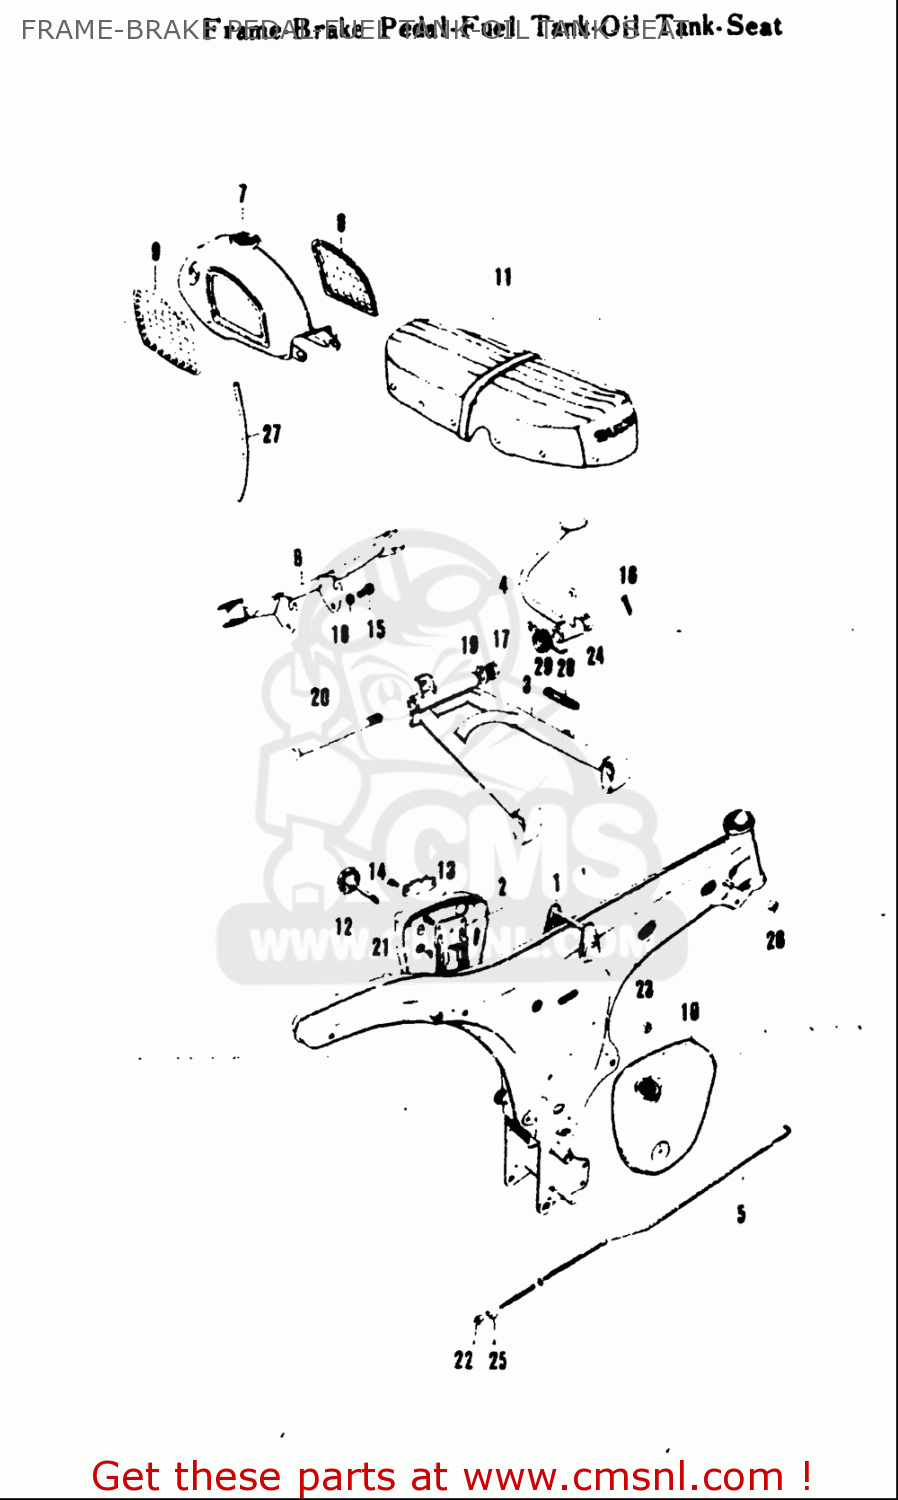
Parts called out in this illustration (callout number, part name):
2	HOLDER,BATTERY
15	BOLT
16	PIN
17	NUT
18	WASHER,LOCK
19	WASHER,LOCK
20	BOLT
21	SCREW(6X10)
22	NUT
23	WASHER(6.5X16X1.2)
24	WASHER(15.5X26X2.3)
25	PIN(11X18)
27	HOSE(5X8.2X2000)
28	SPRING
